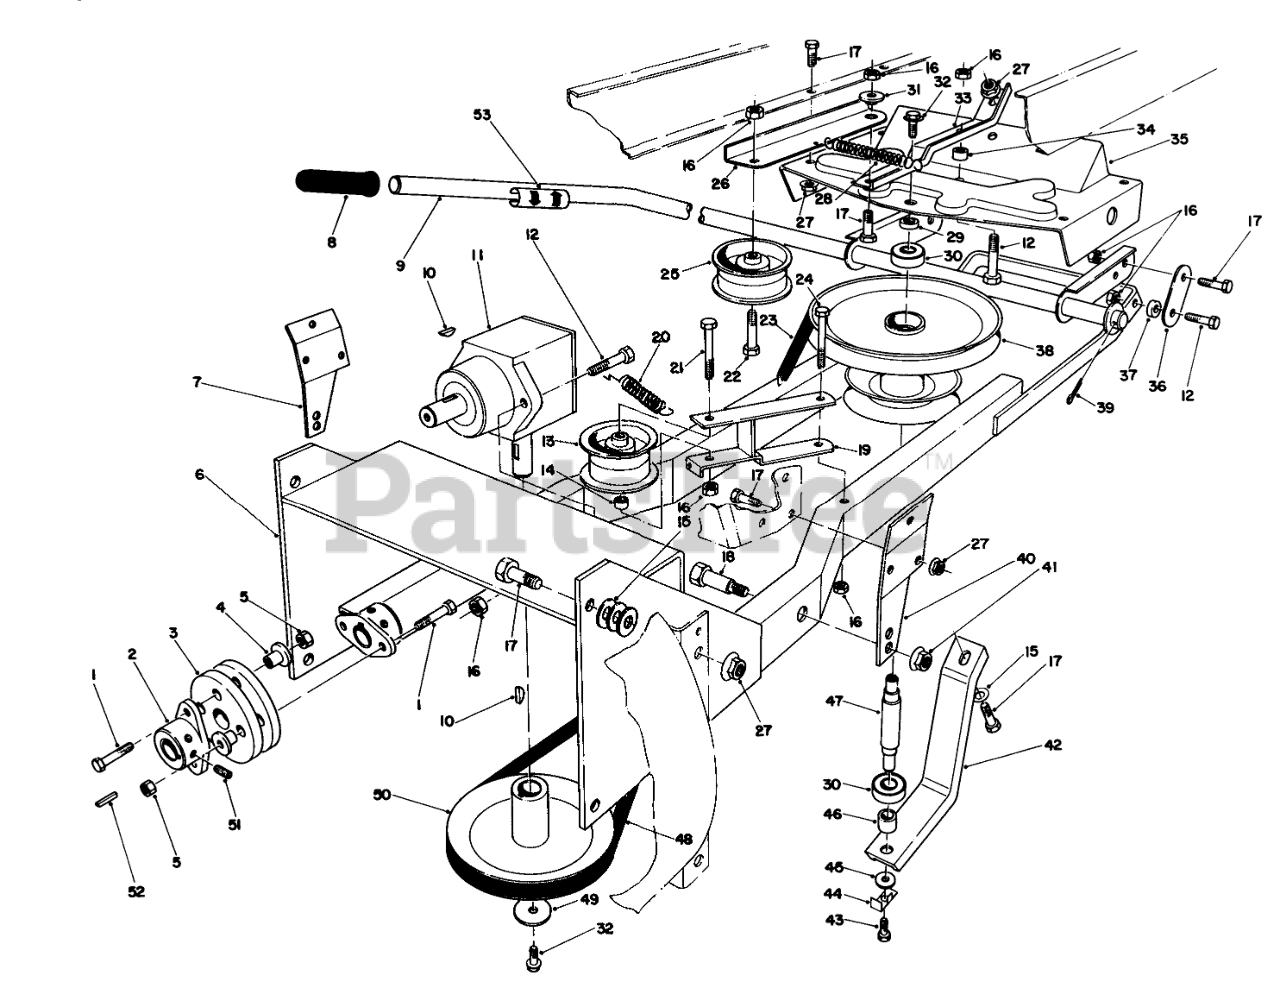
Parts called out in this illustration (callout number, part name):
1	SCREW-HH
2	HUB-COUPLER
3	RUBBER COUPLING
4	Spacer-Rubber Coupling
5	NUT-LOCK, NI
6	Carrier Frame
7	RH FRONT BRKT R
8	Handle Grip
9	Handle-Lift
10	KEY-WOODRUFF
11	Gear Case Assembly
12	SCREW-HH
13	IDLER
14	SPACER
15	WASHER-FLAT
16	NUT-LOCK, NI
17	SCREW-HH
18	SHOULDER BOLT
19	FRT IDLER ARM WA B
20	EXTENSION SPRING
21	SCREW-HH
22	SCREW-HH
23	V-BELT
24	SCREW-HH
25	IDLER BO
26	REAR IDLER ARM B
27	NUT-HHF, WHIZ
28	EXTENSION SPRING
29	UPPER SPACER
30	BEARING-BALL
31	Spacer-Idler Arm
32	SCREW-HHF
33	Support-Frame
34	SPACER
35	REAR FRAME
36	Lift Linkage-Lower
37	SPACER
38	Spindle Housing Assembly
39	PIN-COTTER
40	LH FRONT BRKT R
41	FLANGE NUT 1/2 - 13
42	SHAFT SUPPORT B
43	SCREW-HH
44	Locking Tab
45	WASHER-FLAT
46	Spacer-Lower
47	Shaft-Spindle
48	V-BELT
49	HUB WASHER
50	Pulley
51	SCREW-HSH
52	SQUARE KEY
53	Decal-Lift Control
